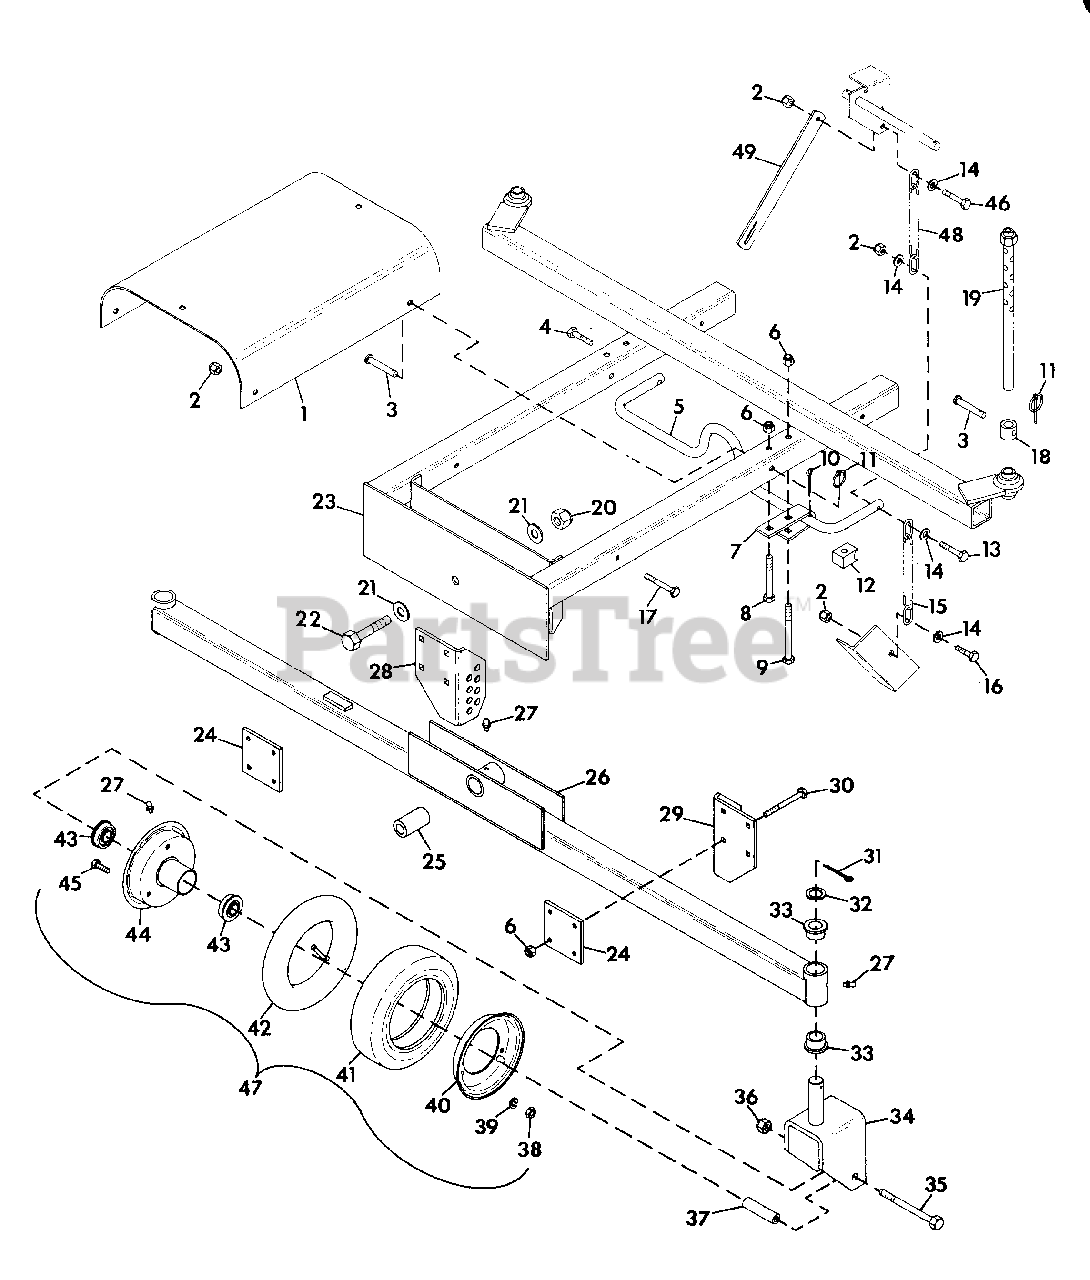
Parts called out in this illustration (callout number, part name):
1	GUARD, PTO SHAFT
2	NUT, LOCK 5/16-18
3	PIN, CLEVIS 3/8X2.62
4	BOLT, HEX 5/16-18X1.50
5	ARM, PIVOT
6	NUT, LOCK 3/8-16
7	BRACKET, AXLE SUPPORT
8	BOLT, HEX 3/8-16X3.00
9	BOLT, HEX 3/8-16X4.00
10	PIN, COTTER 1/8X1.125
11	KLIK PIN
12	STOP, NYLON
13	BOLT, HEX 5/16-18X1.75
14	WASHER, FLAT .406X.812X.065
15	CHAIN, LIFT
16	BOLT, HEX 5/16-18X1.00
17	BOLT, HEX 5/16-18X2.50
18	SPACER, HEIGHT ADJUSTMENT
19	WELDMENT, HEIGHT ADJUSTMENT
20	NUT, LOCK 3/4-10
21	WASHER, FLAT .812X1.469X.130
22	BOLT, HEX 3/4-10X4.50
23	WELDMENT, MOWER FRAME
24	PLATE, ADJUSTMENT CLAMP
25	TUBE, PIVOT
26	WELDMENT, AXLE
27	FITTING, LUBE 1/4-28
28	PLATE, HEIGHT ADJUSTMENT R.H.
29	PLATE, HEIGHT ADJUSTMENT L.H.
30	BOLT, HEX 3/8-16X3.25
31	PIN, COTTER 3/16X1.62
32	RACE, BEARING THRUST
33	BUSHING, PIVOT
34	WELDMENT, CASTER FORK
35	BOLT, HEX 1/2-13X5.00
36	NUT, LOCK 1/2-13
37	BUSHING, WHEEL .520X.750X3.312
38	NUT, HEX 3/8-24
39	WASHER, LOCK 3/8 SP HEAVY
40	WHEEL, HALF PLAIN
41	TIRE, GAUGE WHEEL
42	TUBE, INNER
43	BEARING, GAUGE WHEEL
44	WHEEL, HALF WITH TUBE
45	BOLT, HEX 3/8-24X.75
46	BOLT, HEX 5/16-18X1.25
47	WHEEL, GAUGE
48	CHAIN, LIFT
49	BAR, DECK LIFT
